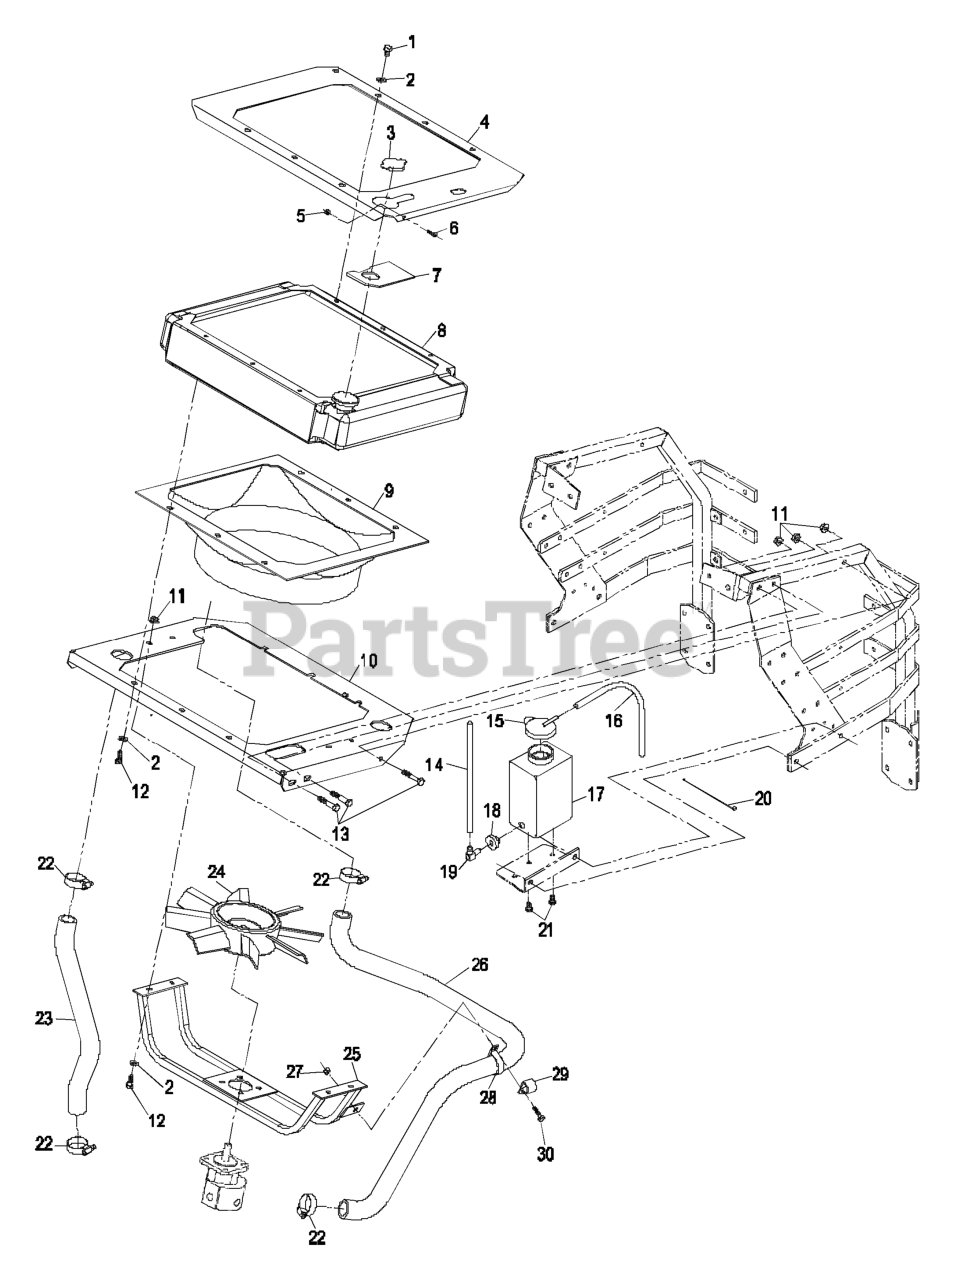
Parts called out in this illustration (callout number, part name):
1	SCREW-HH
2	WASHER-PLAIN
3	CAP-RADIATOR
5	NUT-LOCK, NI
7	SHIELD-FILL NECK, RADIATO
9	SHROUD-COOLING, ENGINE
12	SCREW-HH
13	SCREW-HH
15	CAP-TANK, OVERFLOW
17	TANK-OVERFLOW
20	TIE-CABLE
21	SCREW-HH
25	MOUNT-MOTOR, FAN
26	HOSE-INLET, ENGINE
27	NUT-LOCK, NI
28	CLIP-LOOM
29	CLIP-LOOM
30	SCREW-HH
